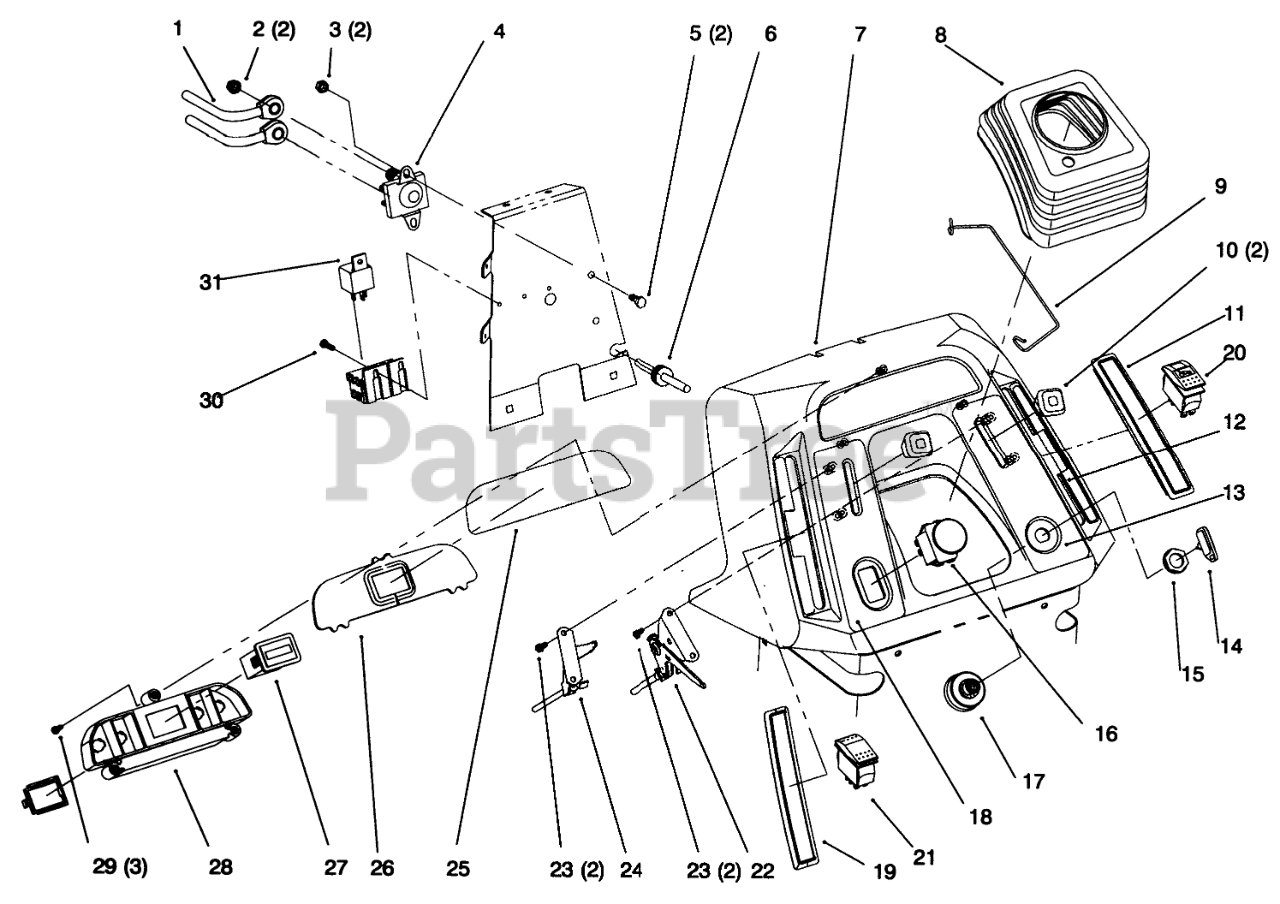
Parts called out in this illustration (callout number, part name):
1	WIRE-21 INCH
2	NUT-KEPS
3	NUT-LOCK, NI
4	Solenoid
5	SCREW-HH
6	GROMMET-RUBBER
8	BOOT-STEERING
9	CLIP-BOOT
11	COVER-SLOT, RH
13	Decal-Throttle/Ignition (Only On: 72046)
13	Decal-Dash (Only On: 72064)
14	KEY-IGNITION
16	SWITCH-PTO
17	SWITCH-IGNITION
18	Decal-Choke/PTO (Only On: 72046)
18	Decal-Dash (Only On: 72064)
19	COVER-SLOT, LH
22	CONTROL-THROTTLE
24	CONTROL-CHOKE
25	Decal-Dash Lens (Only On: 72064)
25	Decal-Dash Lens (Only On: 72046)
26	LENS-DASH
27	HOURMETER
28	Light-Indicator (Only On: 72046)
28	Housing-Indicator Light (Only On: 72064)
29	SCREW-PPH
30	SCREW-PPHTF
31	RELAY
